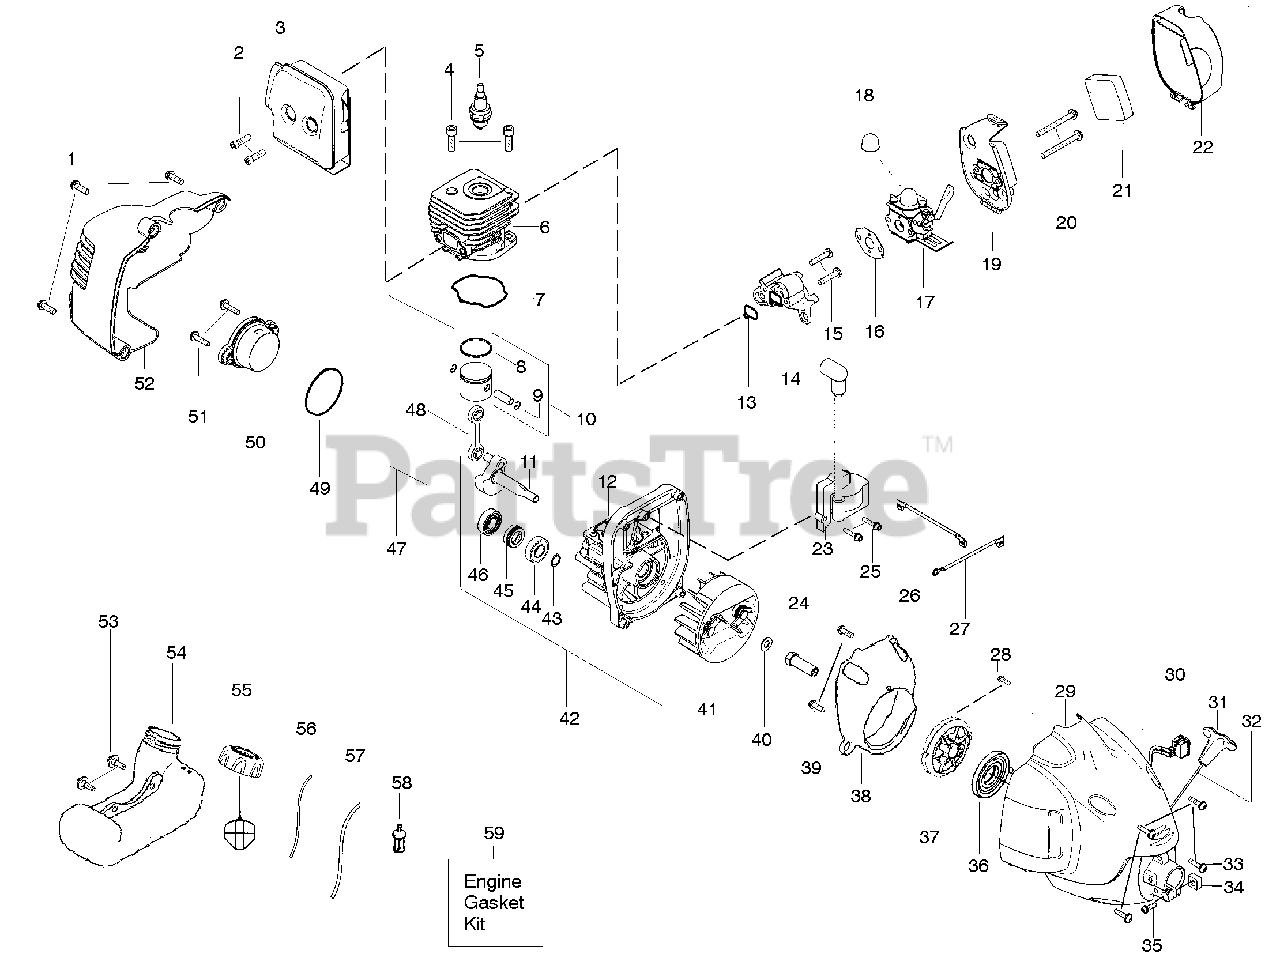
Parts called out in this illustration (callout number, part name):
3	Assy-Muffler/Shield
4	Screw-Cylinder
5	Spark Plug (RCJ 6Y)
7	Seal-Cylinder (kit)
8	Piston Ring
9	Retainer-Piston Pin
10	Kit - Piston
11	Assy-Crankshaft
12	Assy-Crankcase
13	Seal-Cyl/Carb.(kit)
14	Adapter-Carb.
16	Gasket-Carb. (kit)
17	Kit-Carb.Zama (C1U-W19)
17	Kit-Carb.Walbro ( WT-670)
19	Air Box
21	Foam-Air Filter
22	Cover-Air Box
23	Ignition Module
24	Coupling-Drive
26	Assy-Leadwire
27	Assy-Ground Wire
29	Assy.-Fan Hsg
31	Handle-Starter
36	Spring-Starter
37	Kit-Starter Pulley
41	Assy-Flywheel
42	Assy-C'case & C'shaft
43	Retain. Ring-C'shaft
44	Outer Bearing
46	Inner Bearing
47	Kit - Piston / Rod
48	Kit-Conn. Rod Assy
49	O-Ring-C'case (kit)
50	Assy-Plug
53	Retainer-Tank
54	Assy-Fuel Tank
55	Assy-Fuel Cap
56	Kit-Fuel Line (Small)
57	Kit-Fuel Line (Large)
58	Assy-Fuel Pickup
59	Kit-Engine Gasket
